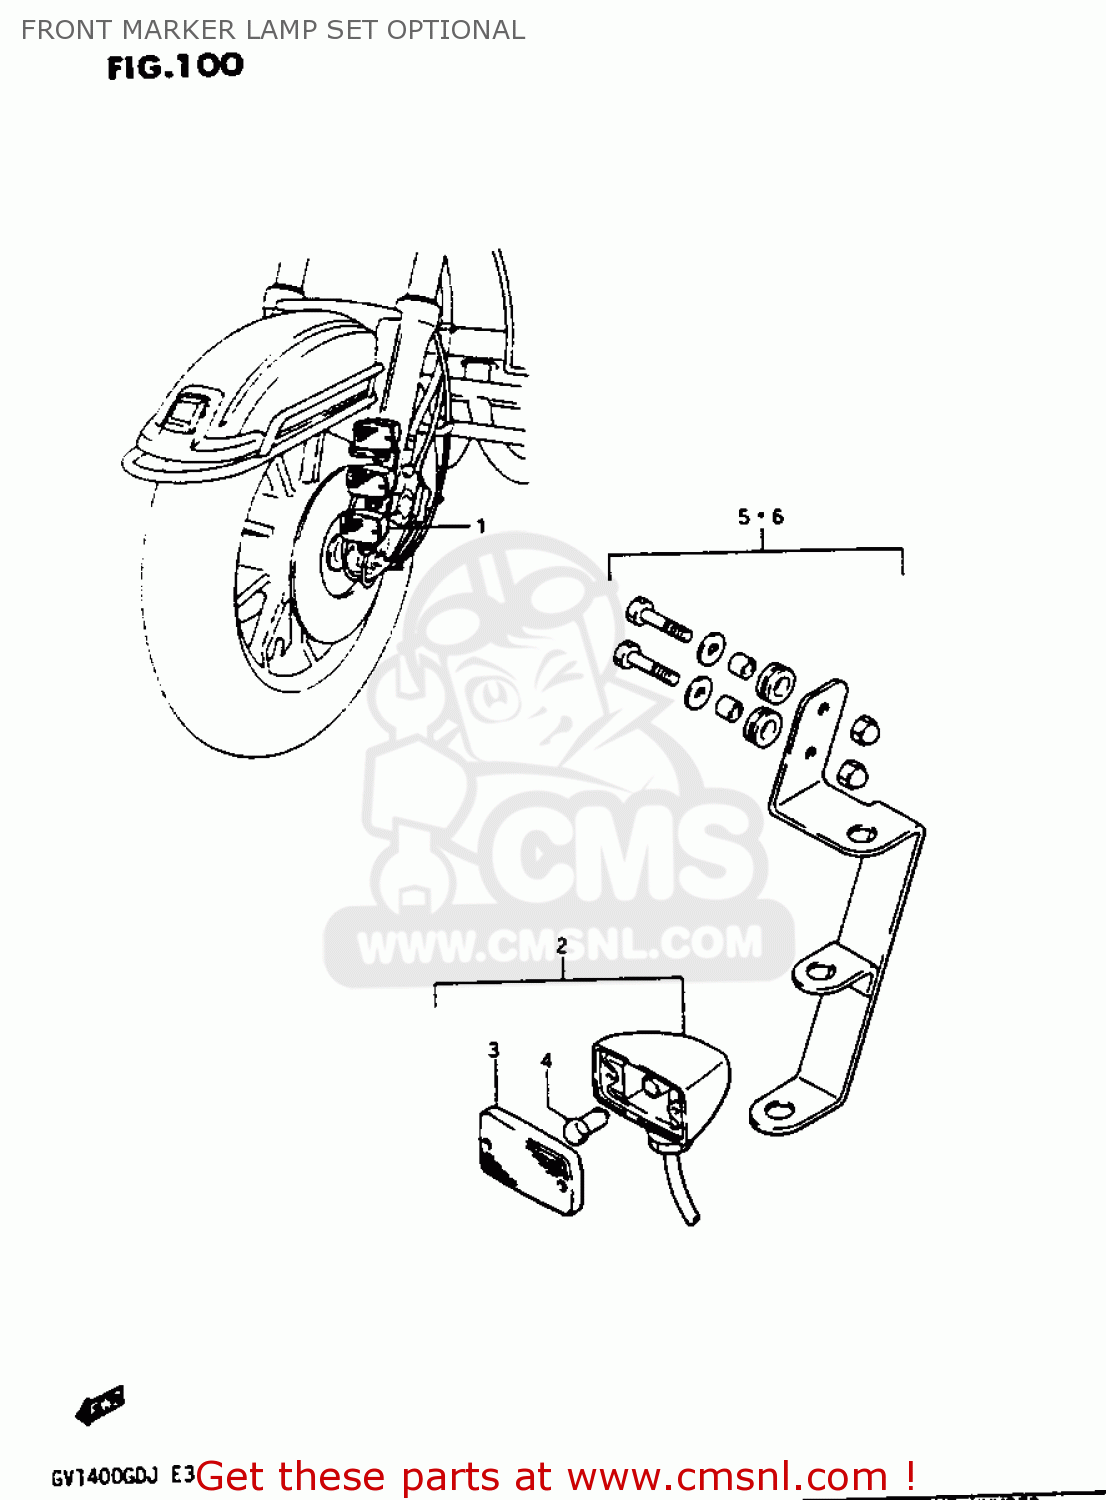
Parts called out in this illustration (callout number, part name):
1	REAR END,MARKER LAMP S
2	LAMP ASSY, FRONT MARKER
3	LENS
4	BULB 12V 3W
5	BRACKET SET, RH
6	BRACKET SET, LH
